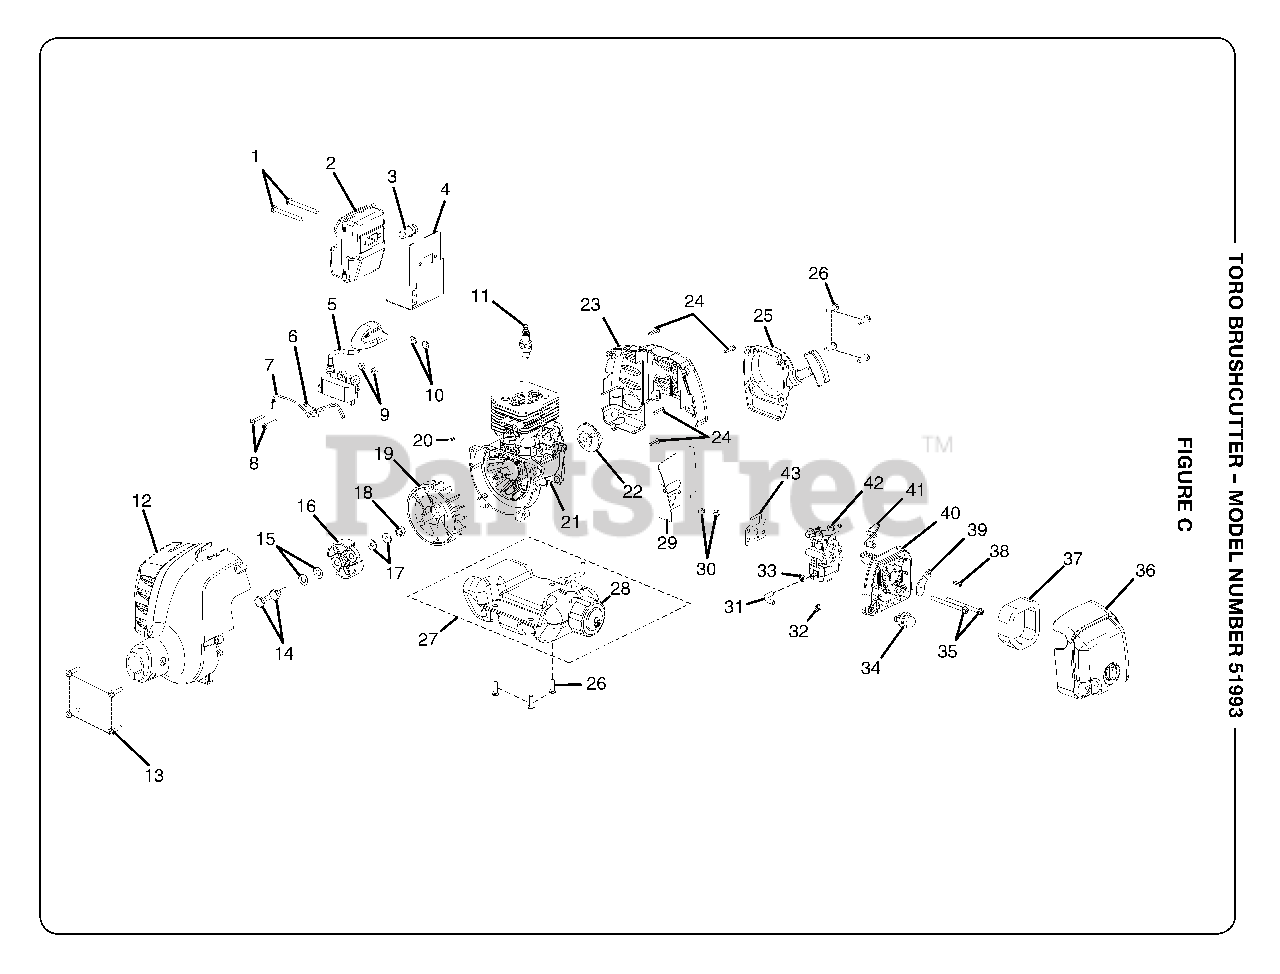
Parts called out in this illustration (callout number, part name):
1	SCREW (M5 X 50 mm TORX SLOTTED RECESSED PAN HD.)
2	MUFFLER ASSEMBLY
4	MUFFLER GASKET
5	COIL BOOT ASSEMBLY
6	LEAD ASSEMBLY, RED
7	LEAD ASSEMBLY, BLACK
8	SCREW (M4 X 22 mm Torx SLOTTED RECESSED PAN HD.)
11	SPARK PLUG
12	FRONT HOUSING ASSEMBLY
13	SCREW (M5 X 20 mm Torx SLOTTED RECESSED PAN HD.)
14	CLUTCH SCREW
15	CURVED WASHER
16	CLUTCH ASSEMBLY
17	WASHER
18	ROTOR NUT
19	ROTOR
20	WOODRUFF KEY (10 mm X 3 mm)
21	SHORT BLOCK ASSEMBLY
22	PULLEY ASSEMBLY
23	ENGINE HOUSING, REAR
24	SCREW (M4 X 16 mm Torx RECESSED PAN HD.)
25	STARTER RECOIL ASSEMBLY
26	SCREW (M5 X 16 mm Torx SLOTTED)
27	FUEL TANK ASSEMBLY
28	FUEL CAP ASSEMBLY
29	INSULATOR GASKET
30	NUT (M5 X .8 mm)
31	FUEL LINE
32	HOSE CLIP
33	HOSE CLIP
34	PRIMER ASSEMBLY
35	SCREW (M5 X 60 mm SLOTTED RECESSED PAN HD.MACHINE)
36	COVER ASSEMBLY
37	ELEMENT
38	SCREW (M4 X 12 mm SLOTTED RECESSED PAN HD.)
39	CHOKE PLATE
40	CARBURETOR PLATE
41	CHOKE LEVER
42	CARBURETOR ASSEMBLY
43	CARBURETOR GASKET
